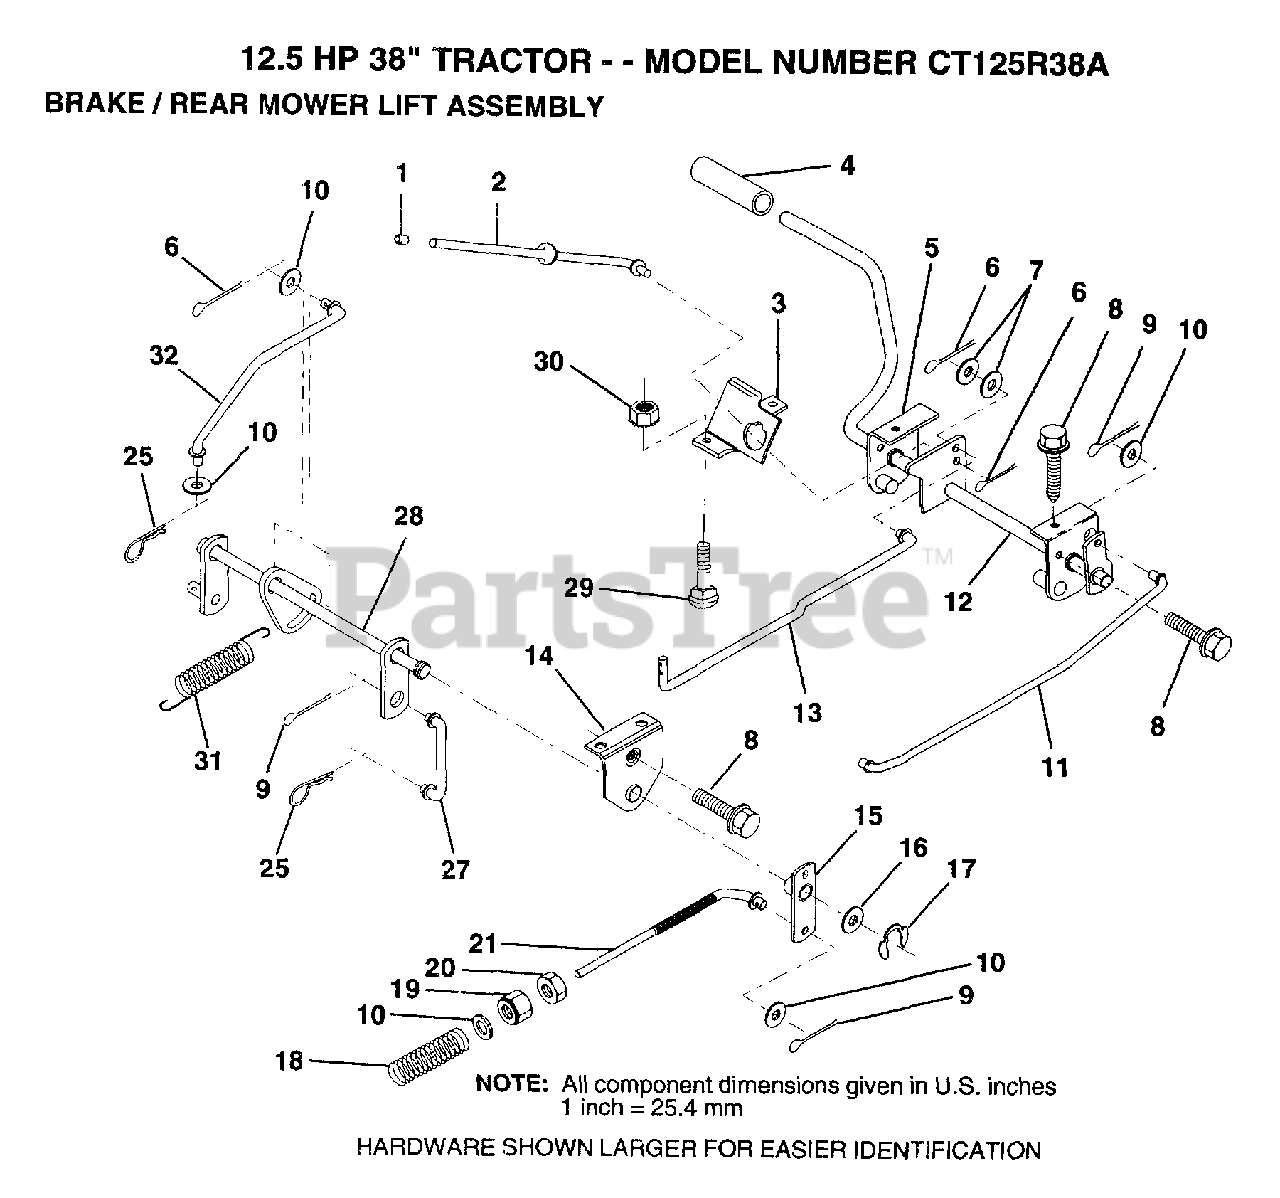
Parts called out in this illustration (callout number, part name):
1	PLUNGER CAP T
2	"ROD,PARK BRAKE"
3	"BRKT,PARK BRAKE"
4	PEDAL COVER T
5	BRK ASM CLUT LH
7	WASHER
8	SCREW LT
9	COTTER PIN
10	WASHER
11	"ROD,FRT BRAKE"
12	ASM CLUTCH/BRK PD
13	"ROD,CLUTCH"
14	"BRKT,LIFT SHAFT"
15	BRAKE PIVOT ARM
16	WASHER T
17	KLIP RING
18	SPRING ROD LT
19	NUT
25	SPRING.RETAINER
27	LINK LIFT REAR LR
28	LIFT ASM MWR RE
31	COUNTER SPRING
32	LINK LIFT LEVER
